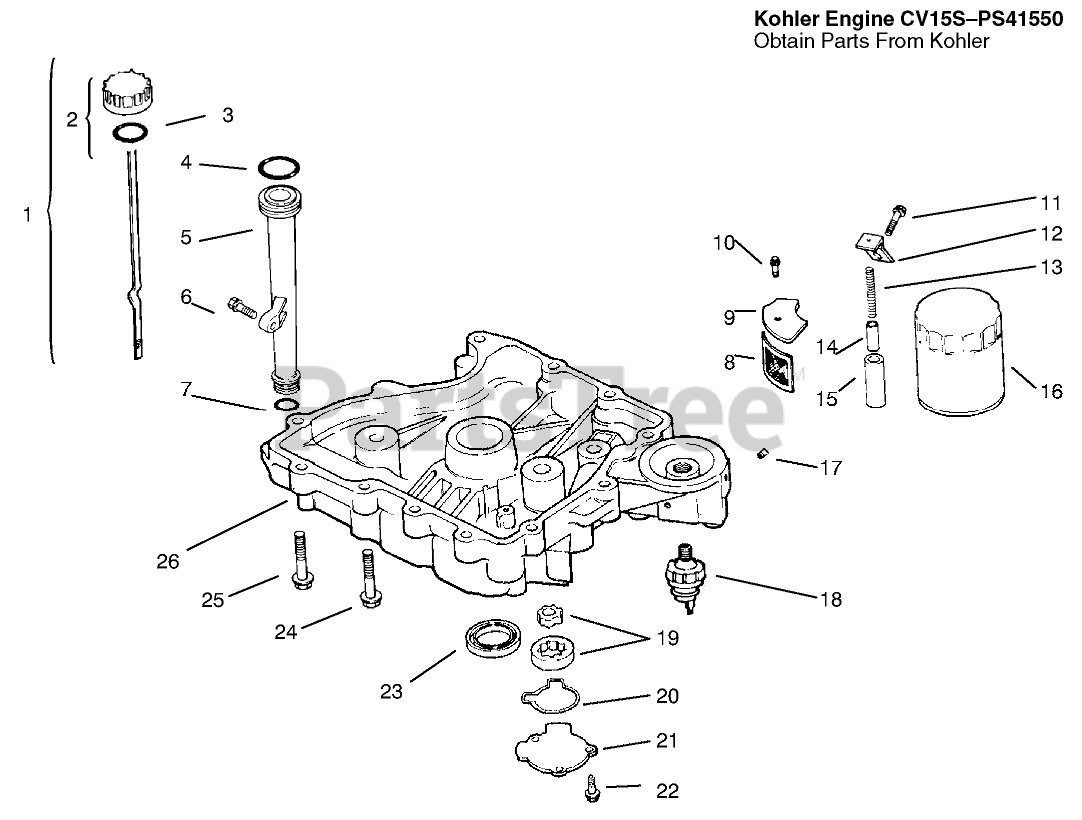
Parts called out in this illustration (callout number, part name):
1	Dipstick INC 2-3
2	Kit-Oil Fill Cap
3	"O"Ring
4	"O"Ring
5	Tube-Oil Fill
7	"O"Ring
8	Screen-Oil Pickup
9	Cover-Oil Screen
10	Screw-HF
11	Screw
12	Bracket-Oil Pump Relief
13	Spring-Oil Relief Valve
14	Piston-Oil Relief Valve
15	Body-Oil Relief Valve
16	Filter-Oil
17	Plug
18	Switch, pressure
19	Pump-Oil
20	"O"Ring-Pump Cover
21	Cover-Oil Pump
22	Screw-HF
23	Seal-Crankshaft
24	Screw
25	Screw
26	Pan-Oil
